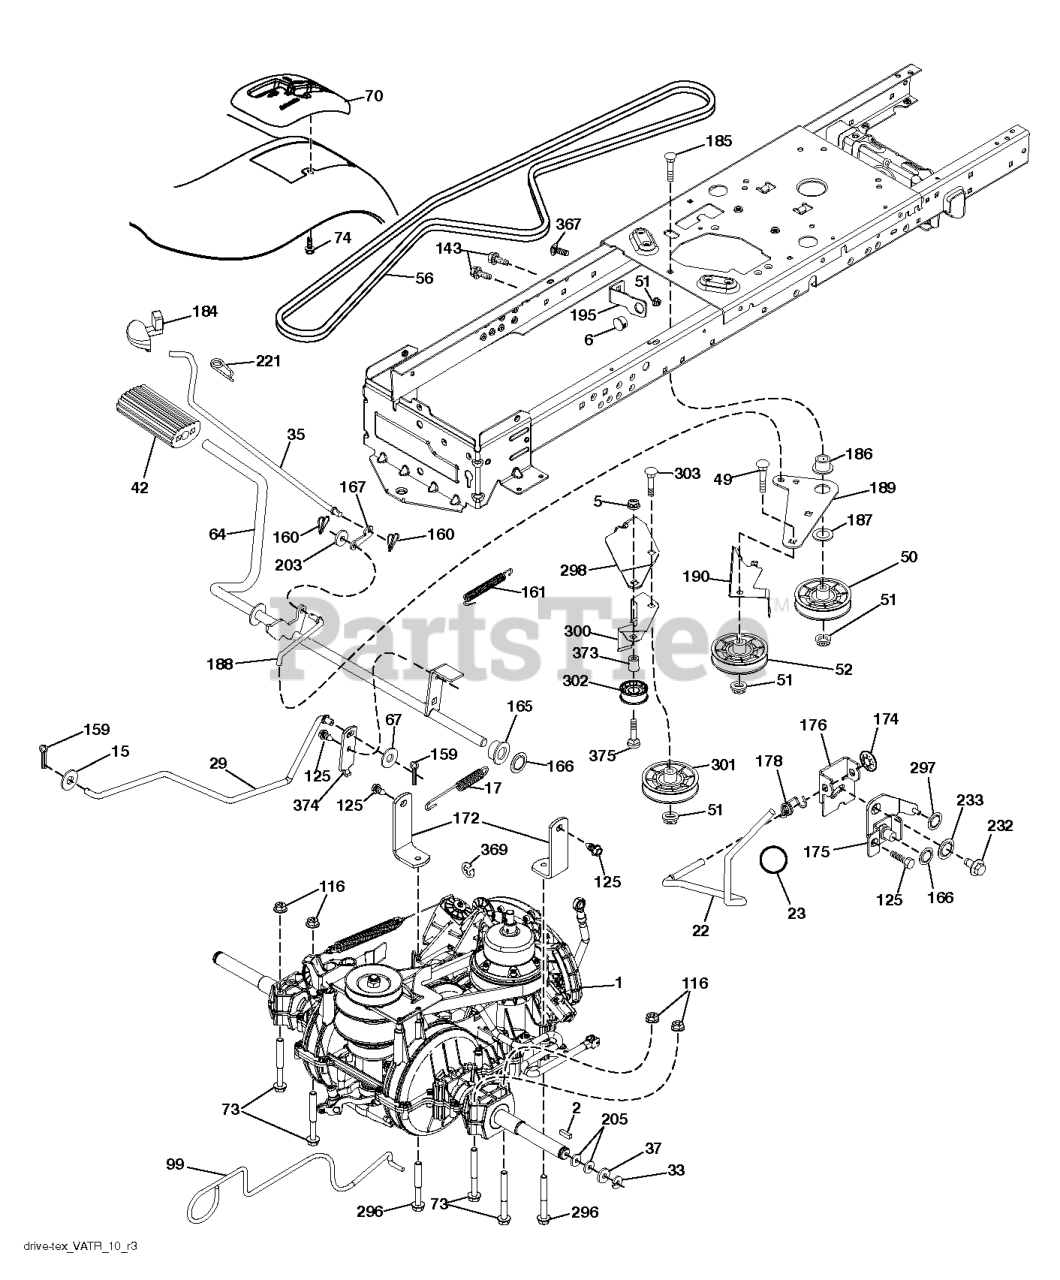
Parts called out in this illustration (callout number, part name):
2	SQUARE KEY
5	LOCKNUT
6	BUSHING.SNAP.NYL.BLK.
15	WASHER
17	SPRING.BRAKE.K46.GREEN
22	ROD.SHIFT.LT.TEX.VARIATOR
23	KNOB.DELUXE.(PISTOL.GRIP).BLAC
29	RB ROD.BRAKE.VARIATOR.SD2
35	ROD.BRAKE.PARTK.HUSQ.TEX
37	WASHER.HARDENED
42	PEDAL COVER T
49	BOLT
50	IDLER.FLAT.910.OFFSET
51	NUT LOCK FLG 3/8-16 UNC
52	IDLER.V-GROOVE.910.OFFSET
56	BELT.DRIVE.MOWER.TEX.42"
64	SHAFT SUB ASM PEDAL BRAKE
67	WASHER
73	BOLT HEX 5/16-18 GR 5
74	SCREW.HI-LO.CONSOLE
99	ROD.BYPASS.VARIATOR.GEN2
116	NUT LOCK HEX FLANGE 5/16-18
125	SCREW
143	SCREW LT
159	COTTER PIN
160	RETAINER CLIP
161	SPRING, RETURN LT
165	BUSHING.SHAFT.BRAKE.HAND
166	NUT.PUSH.625
167	LATCH.BRAKE.SPRING
172	STRAP.TORQUE.VARIATOR
174	NUT.PUSH.500.2006
175	SHAFT.ASM.SHIFT.VARIATOR
176	ARM.CLEVIS.ROD.SHIFT
178	SPRING.SHIFT.GT2006
184	RB HANDLE.PARKG.BRK.HUS/PRED
186	SPACER.RETAINER
187	WASHER 12/32X2X10GA
188	RP.LINK.CLUTCH.GROUND.DRIVE
189	BELLCRANK.GROUND.DRIVE.TEX.
190	KEEPER.BELLCRANK.DRIVE
195	BRACKET.BRAKE.BRAKE.VAR.SD
203	WASHER
221	RETAINER.SPRING.CLIP.H
232	BOLT FIN HEX 7/16-14 X 1
233	WASHER SERRATED
296	SCREW.THDROL.5/16-18
297	NUT.PUSH.1/4
298	BRACKET.MOUNT.IDLERS
300	KEEPER.IDLERS.REAR.VARIATOR
301	PULLEY.IDLER.V-GROOVE
302	RB PULLEY.IDLER.FLAT.2.0"OD RP
303	BOLT CARRIAGE
367	BOLT D
369	CLIP.E.VARIATOR WSL
373	SPACER.IDLER
374	ARM.CONTROL.BRAKE
